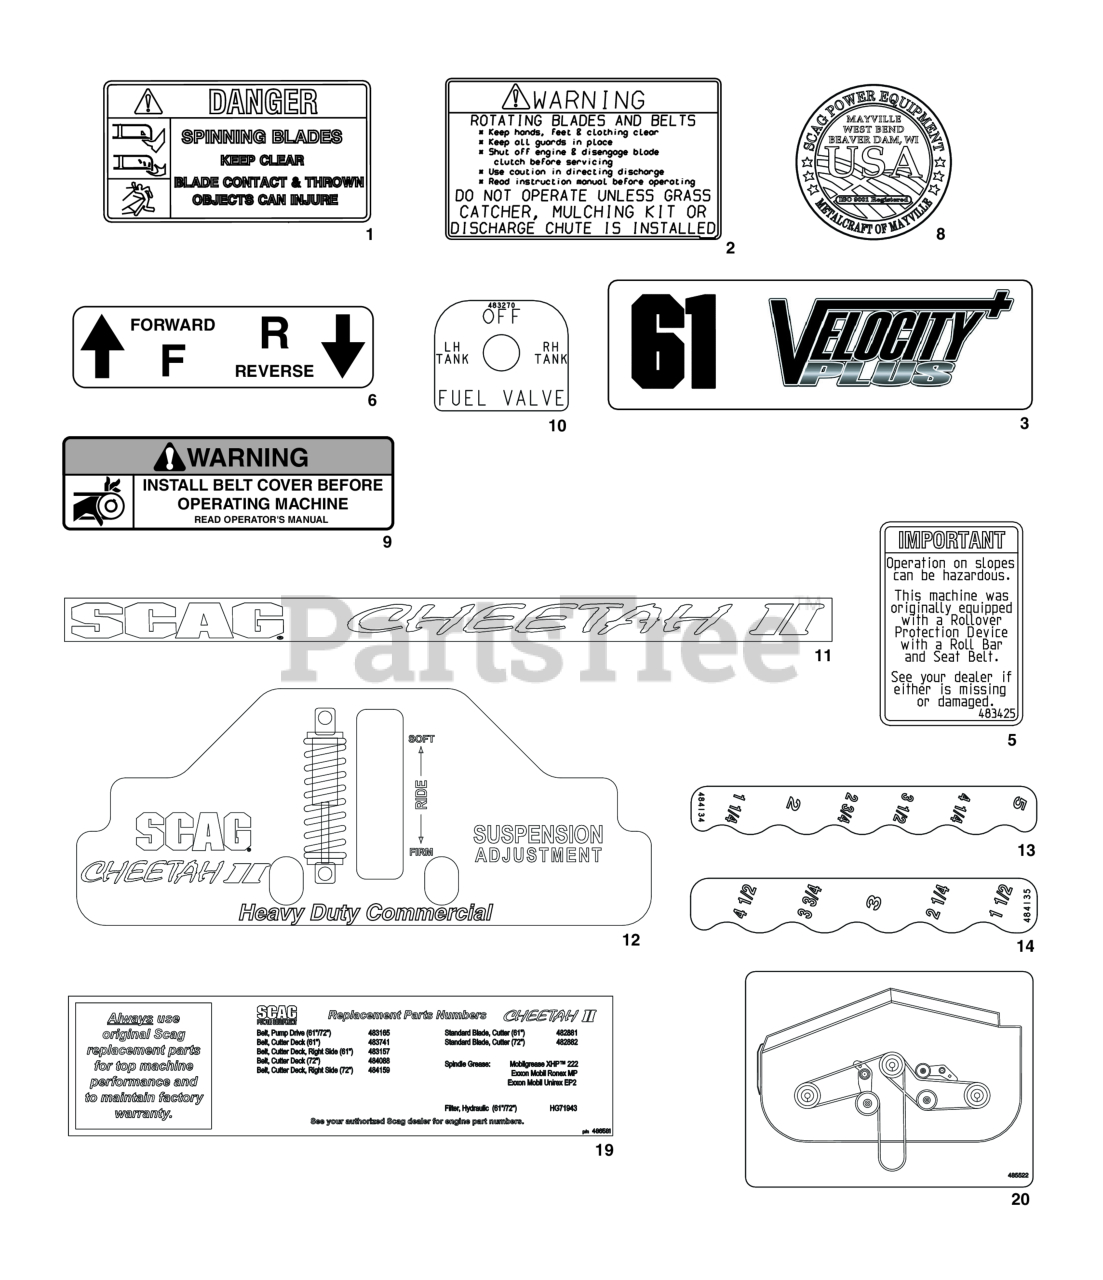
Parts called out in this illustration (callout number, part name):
1	Decal, Danger-Spinning Blades
2	Decal, Warning - Rotating Blades
3	DECAL, VELOCITY PLUS - 61
3	Decal, Velocity Plus - 61RD
5	Decal, ROPS
6	Decal, Traction Control
8	Decal, Metalcraft - USA
9	Decal, Warning - Belt Cover
10	Decal, Fuel Shut Off
11	Decal, Scag Cheetah II
12	Decal, Suspension Adjustment
13	Decal, Deck Height - LH
14	Decal, Deck Height - RH
19	Decal, SCZII Replacement Parts
20	Decal, Belt Routing (61V)
